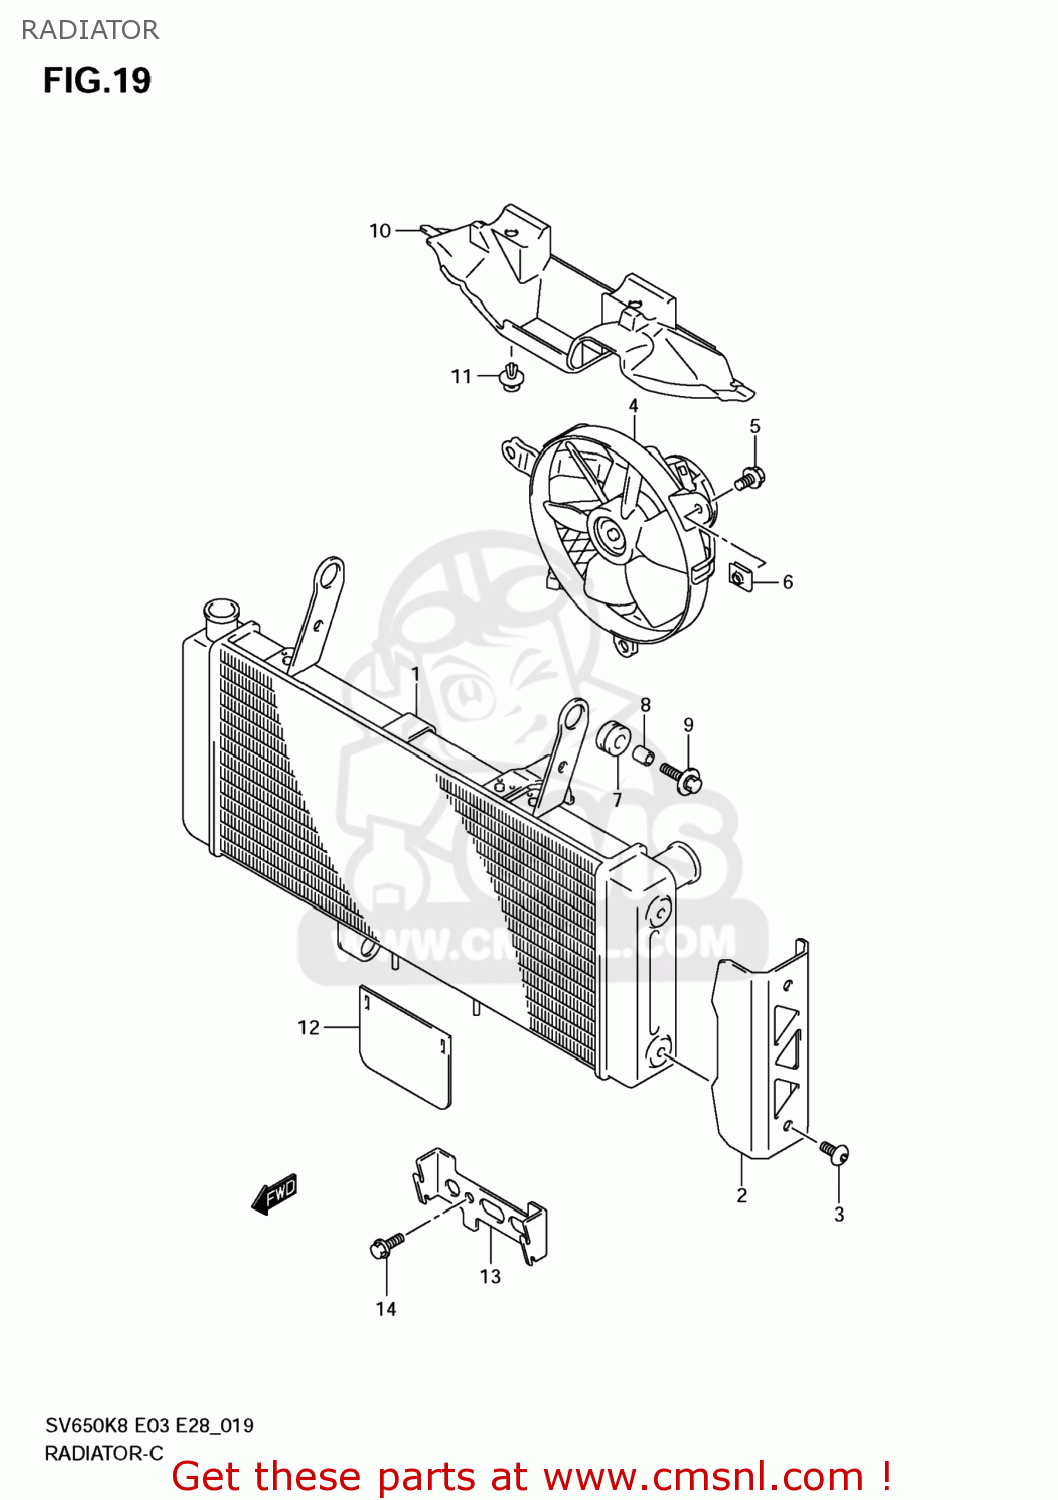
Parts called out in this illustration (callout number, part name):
1	RADIATOR ASSY,WATER
2	COVER,RADIATOR
3	SCREW(6X12)
4	FAN ASSY,RADIATOR
5	BOLT
6	NUT,FAN ASSY
7	CUSHION
8	SPACER(6.5X10X12)
9	BOLT(6X25)
10	SHIELD,RADIATOR HEAT
11	CLIP
12	RUBBER,RADIATOR UNDER
13	BRACKET,RADIATOR UNDER RUBBER
14	BOLT
